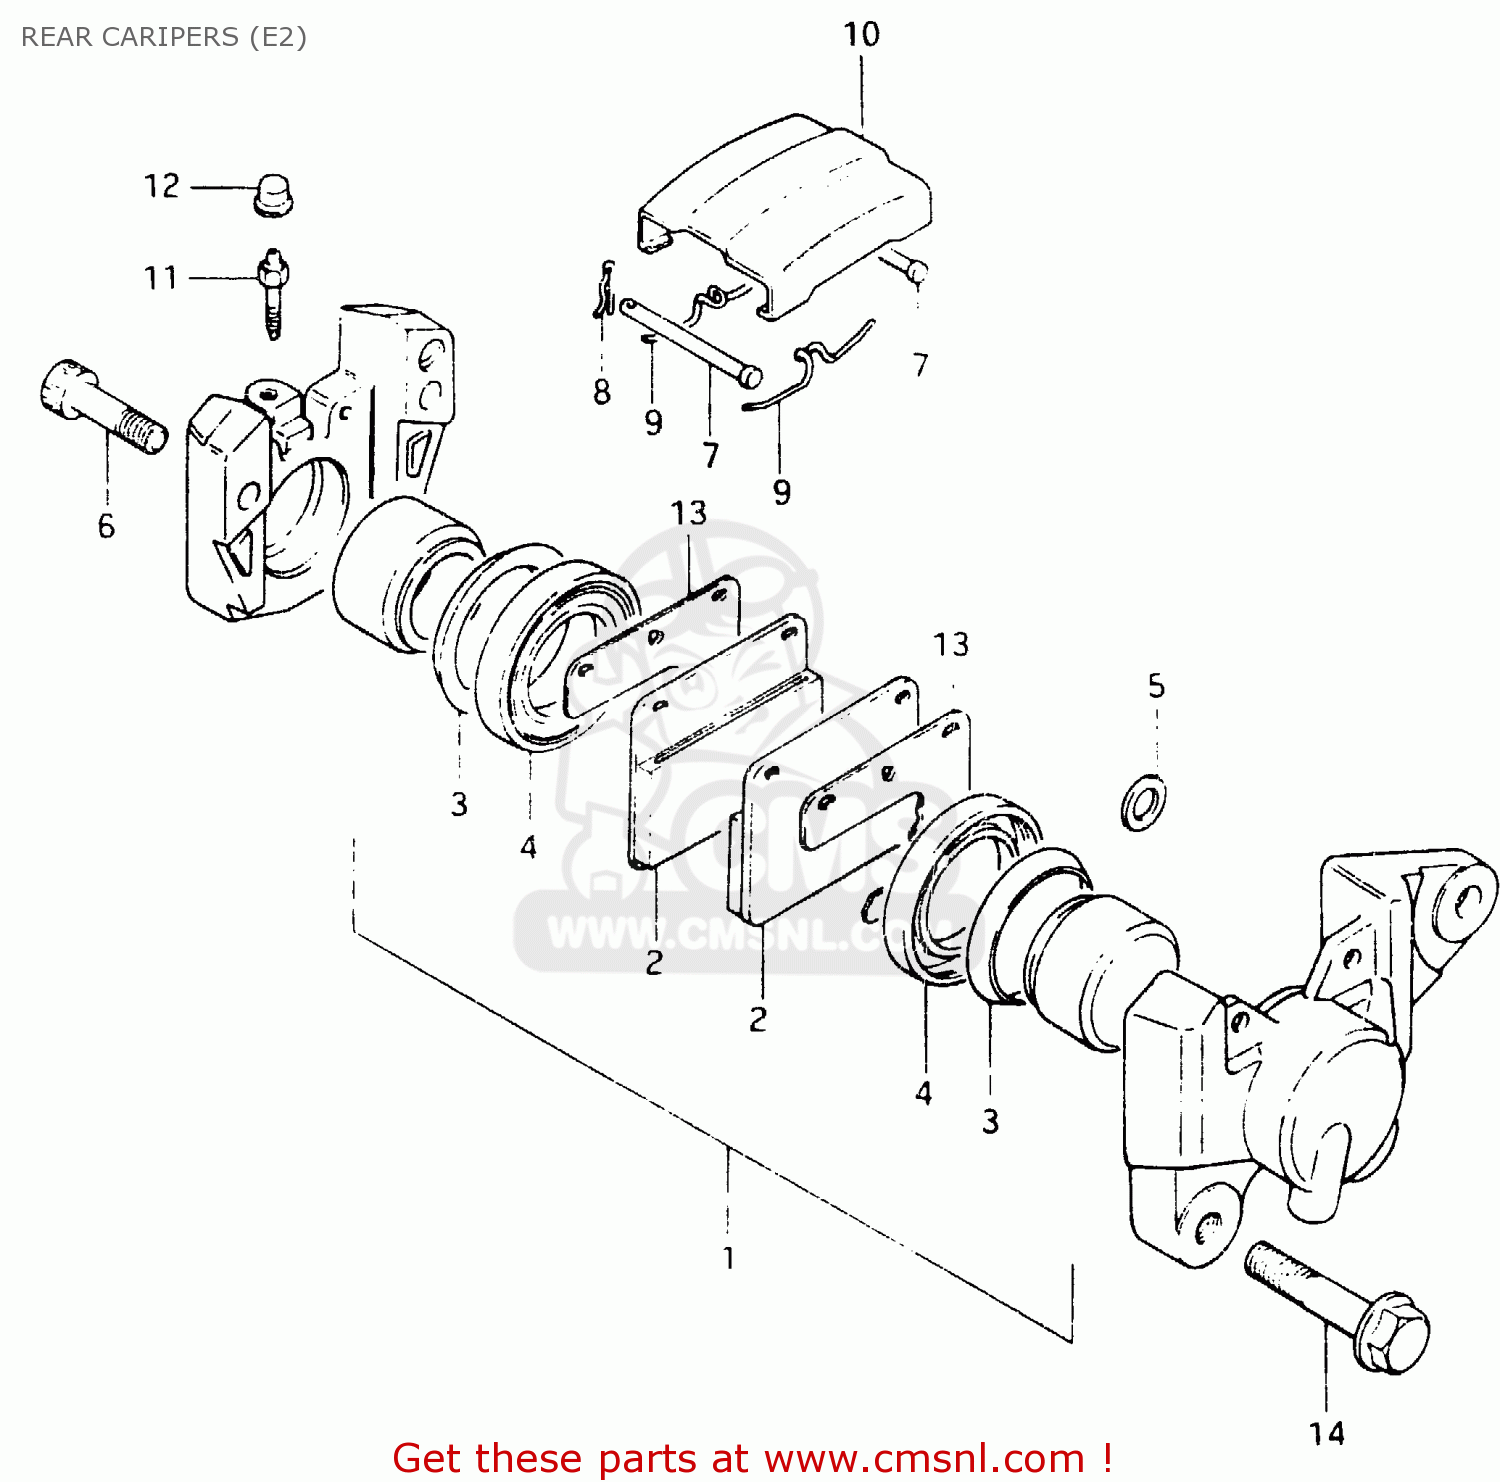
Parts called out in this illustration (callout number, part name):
1	PISTON SET
2	PAD,BRAKE (MCA)
3	SEAL,PISTON
4	BOOT,PISTON
5	SEAL,JOINT
6	BOLT,CALIPER HOUSING
7	PIN,PAD
8	CLIP,PAD PIN
9	SPRING
10	COVER,DUST
11	BLEEDER
12	CAP,BREATHER
13	SHIM,RR CALIPER
14	BOLT
